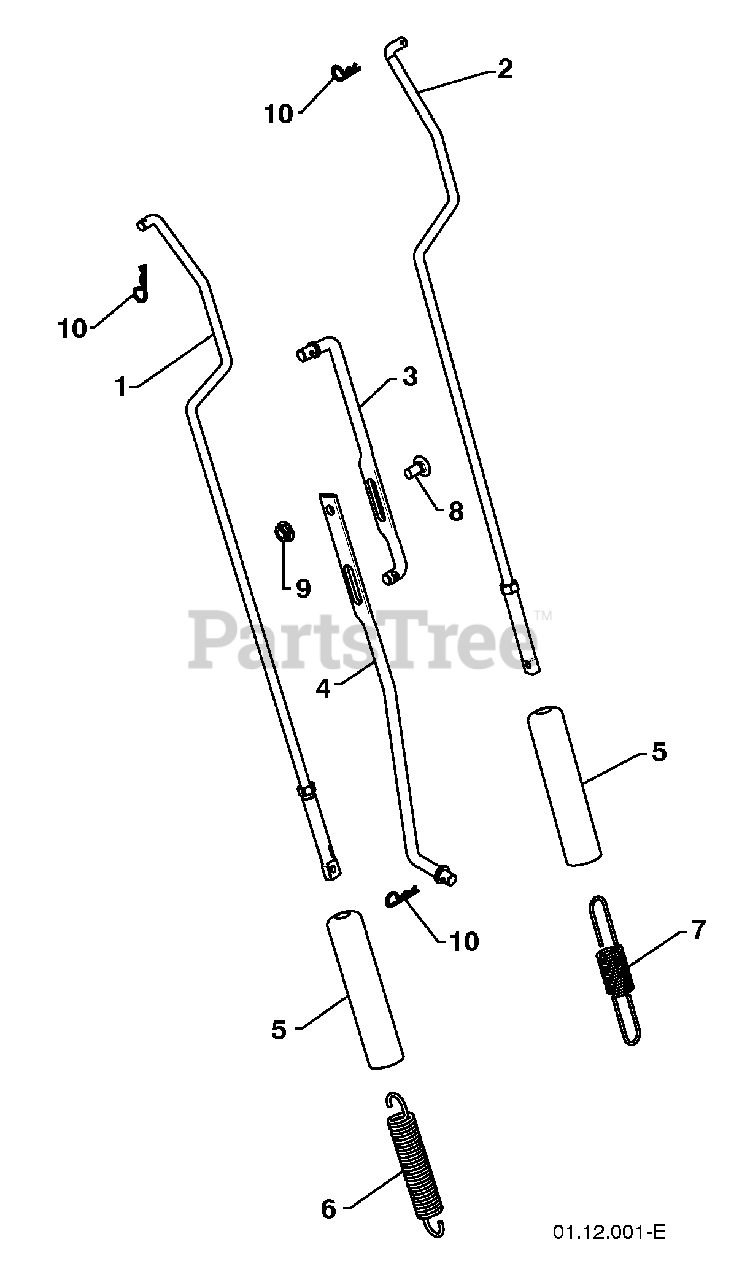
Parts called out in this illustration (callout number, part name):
1	IMPELLER ROD
2	TRACTION ROD
3	SHIFTER ROD TOP
4	SHIFTER ROD BOTTOM
5	SPRING SLEEVE
6	IMPELLER SPRING
7	TRACTION SPRING
8	CARRIAGE BOLT 5/16-18 X .75
9	NUT 5/16-18
10	RETAINER
